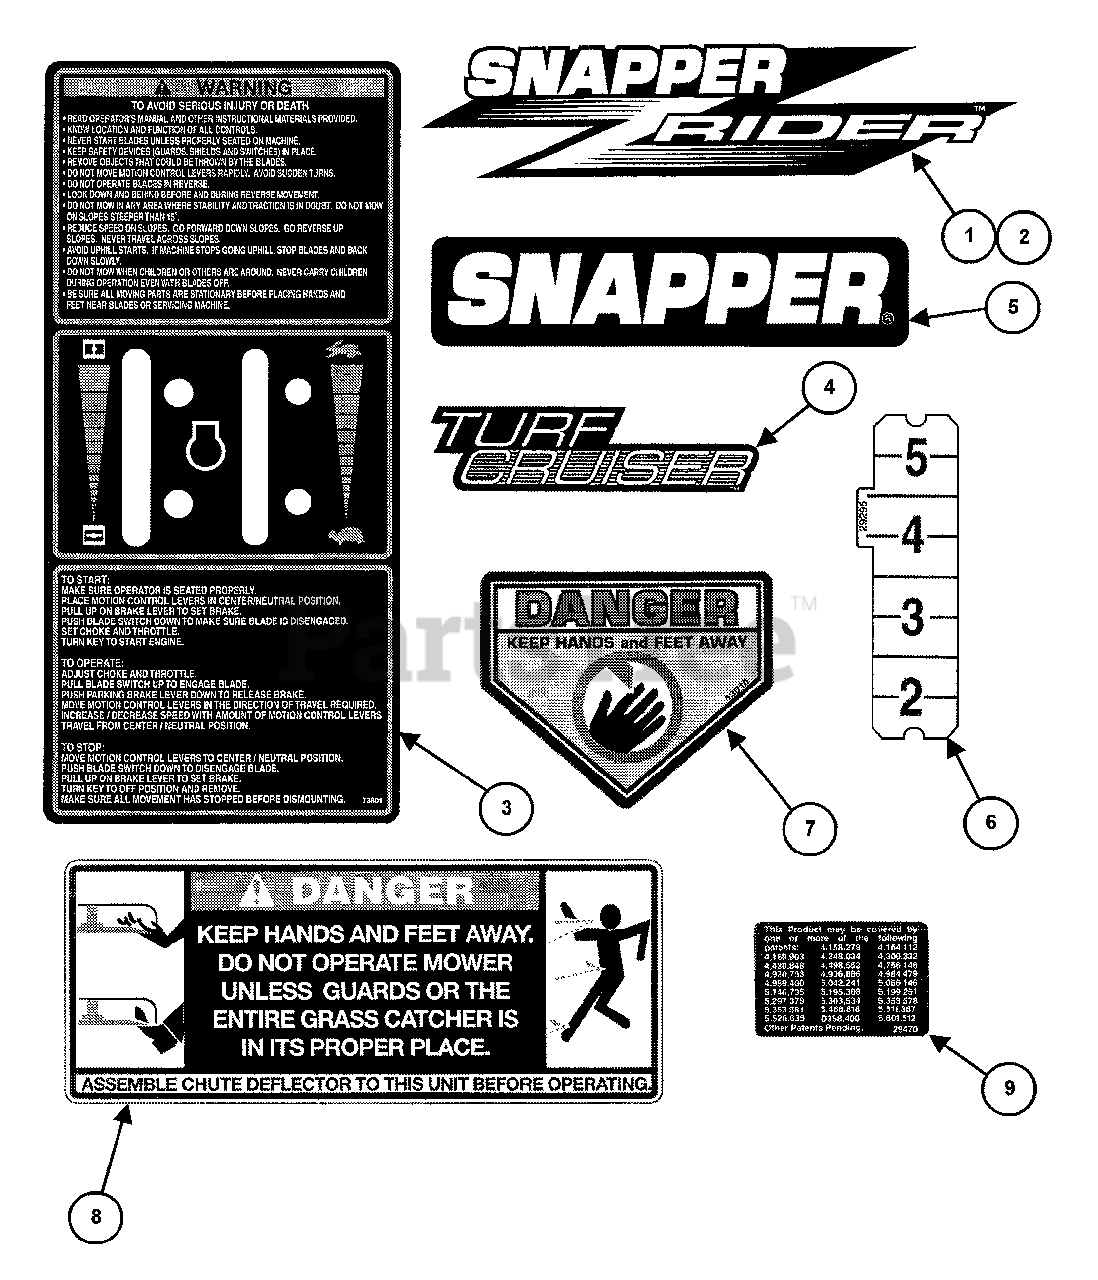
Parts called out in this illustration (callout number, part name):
1	LOGO, Front 16.33" Long
2	LOGO, Side 24.5" Long
3	DECAL, Throttle/Choke
4	DECAL, Name ZF2200K
5	DECAL, SNAPPER
6	DECAL, Height-of-Cut
7	DECAL, Warning (CPSC Cut-Finger)
8	DECAL, Danger
9	DECAL, Patent Numbers
